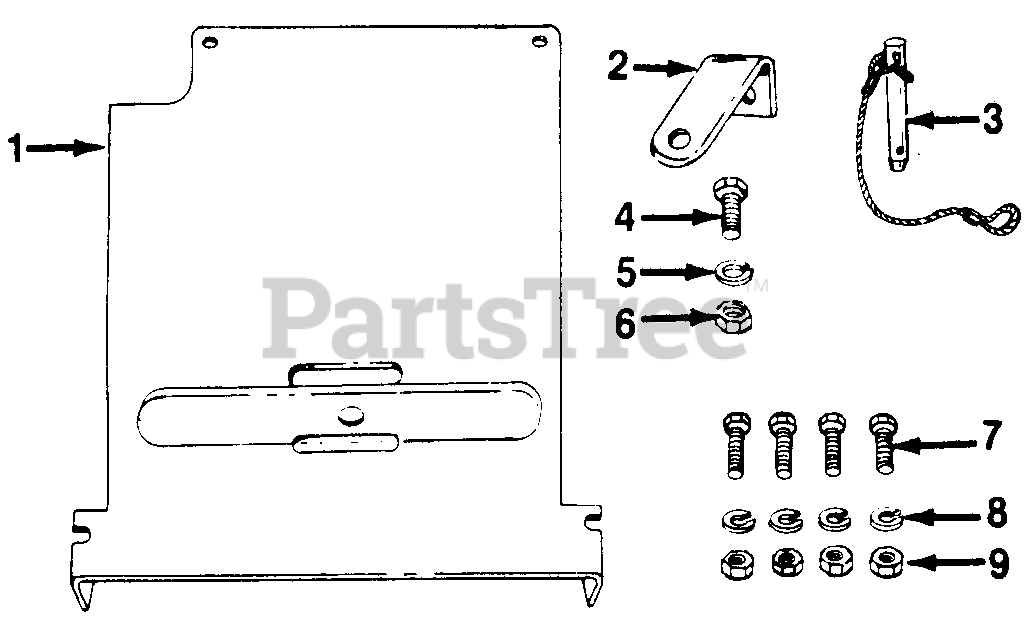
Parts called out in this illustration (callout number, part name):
1	Hitch Plate
2	Hitch Bracket
3	Hitch Pin
4	Hex Scr. 3/8 16 x 1 " Lg.
5	L-Wash. 3/8" Scr.
6	Hex Nut 3/816 Thd.
7	Hex Scr. 5/16-18 x .75" Lg.
8	L-Wash. 5/16" Scr.
9	Hex Nut 5/16-18 Thd.
